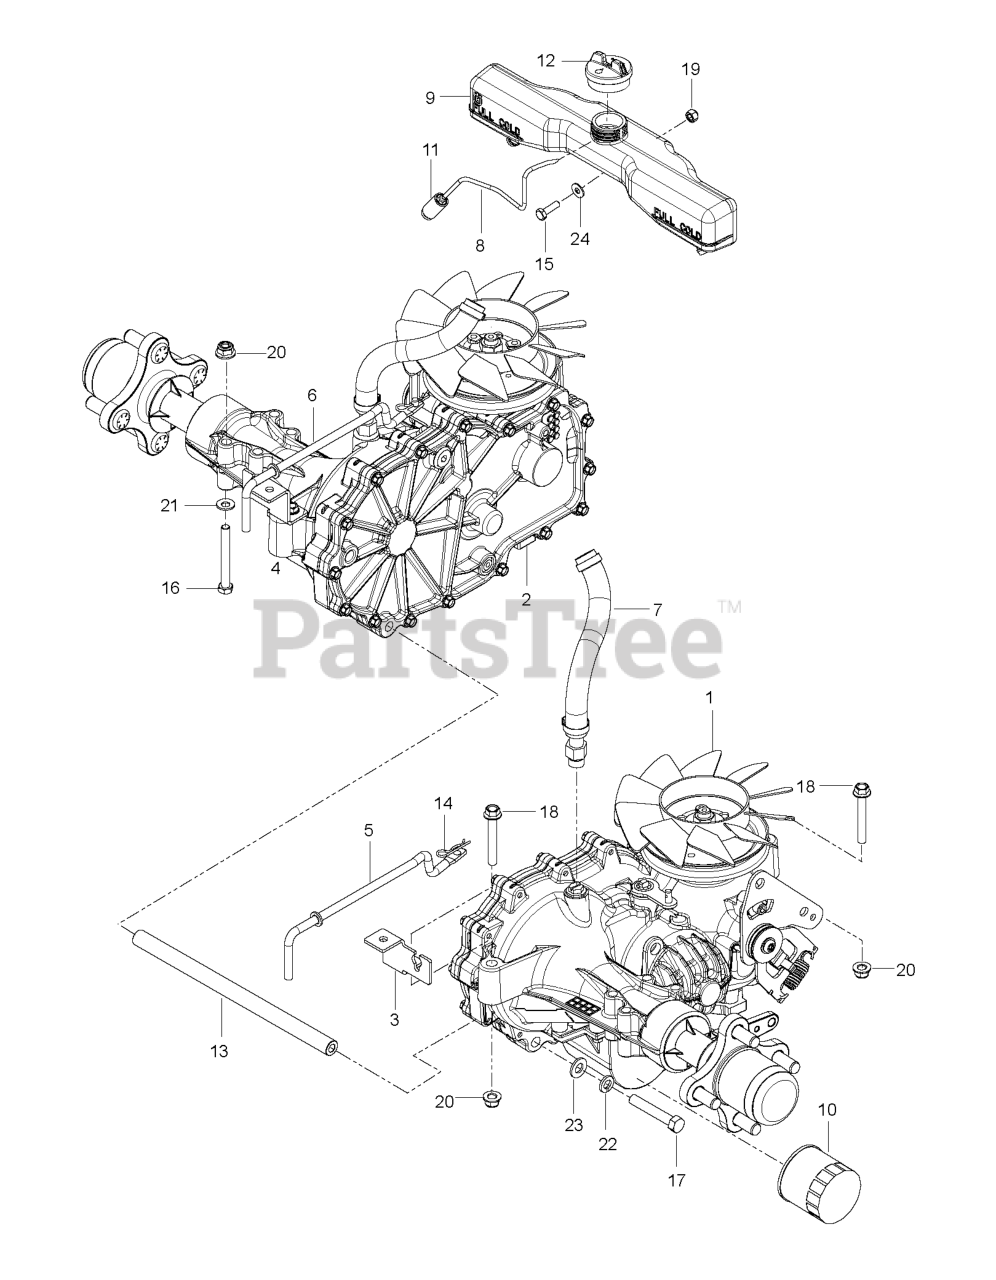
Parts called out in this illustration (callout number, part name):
1	HG_TRANS, ZT-3400, LT
2	HG_TRANS, ZT-3400, RT
3	BRACKET.TRANS.LT.BLACK
4	BRACKET, TRANS, RT BLACK
5	LINKAGE, LEFT BYPASS
6	LINKAGE, RIGHT BYPASS
7	HOSE ASSY, EXPANSION
8	TANK HOSE
9	TANK EXPANSION W/CAP
10	HG_FILTER, ZT4800 52114
11	FUEL PICK-UP ASSY
12	CAP EXPANSION W/SEAL
13	TUBE, SPACER, 3400
14	HAIRPIN #2
15	HCS 1/4-20X7/8 GR5
16	BOLT HEX
17	HCS 3/8-16X2-1/4 LOC PATCH GR8
18	HHFS 5/16-18 X 2.25 GD 5
19	RP_NUT 1/4-20 NYLOC
20	5/16-18 NYLOC FLANGE NUT
21	WASHER
22	SLW 3/8 STD
23	WASHER 3/8 SAE FLAT
24	WASHER 1/4 SAE
